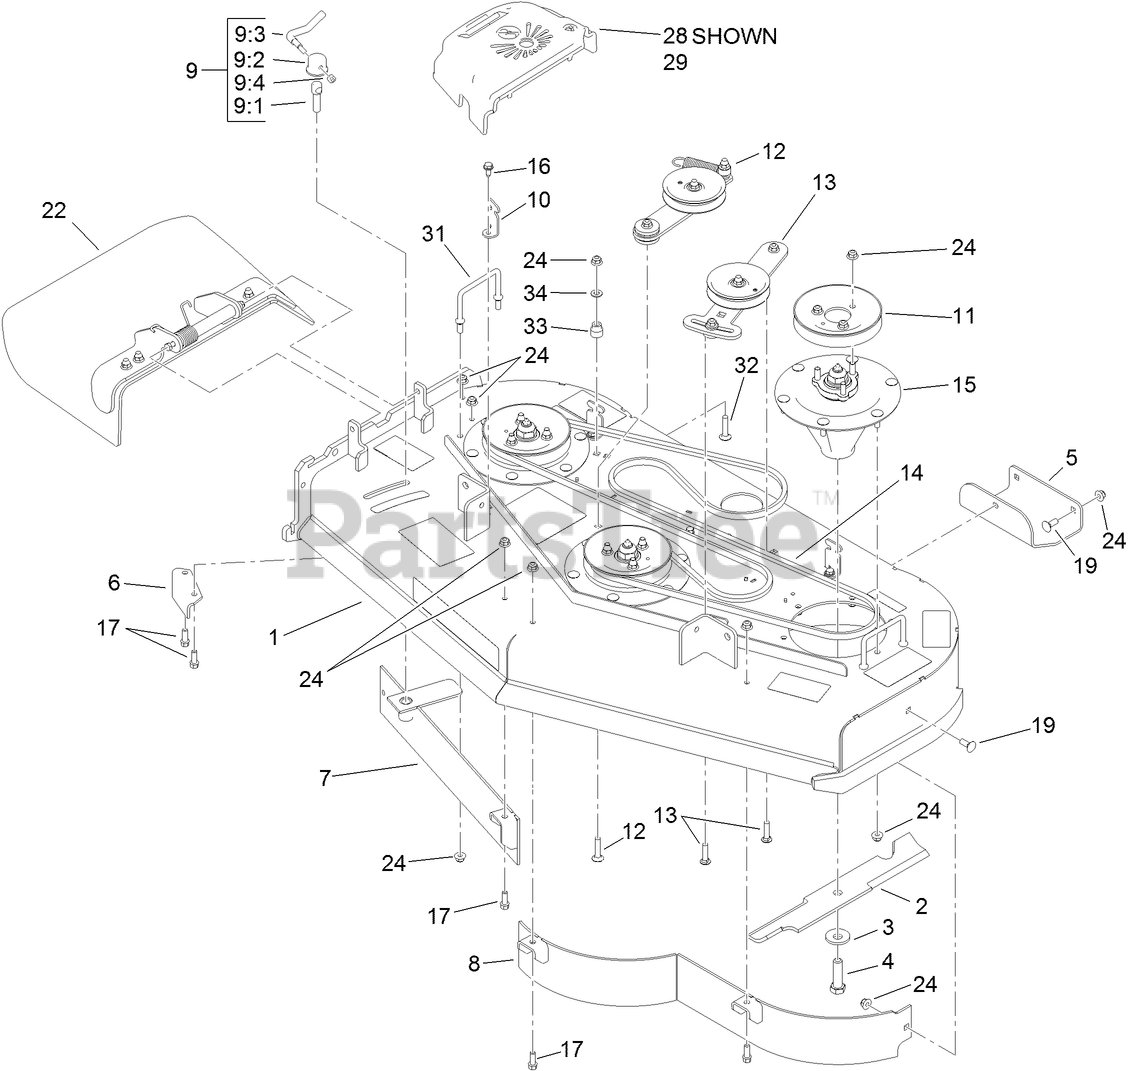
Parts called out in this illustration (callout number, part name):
1	DECK ASM
2	BLADE-16.5 INCH (HIGH FLOW)
3	Washer-Blade Bolt, Heavy
4	SCREW-BLADE
6	BAFFLE-DISCHARGE
7	BAFFLE ASM
8	48 INCH BAFFLE ASM
9	LEVER ASM
9:1	Screw-Lock
9:2	CAP-LOCK
9:3	Lever-Lock
9:4	NUT-LOCK, NI
10	BRACKET-COVER
11	PULLEY
12	IDLER ARM ASM
13	IDLER ADJUST ASM
14	BELT-V
15	SPINDLE ASM
16	SCREW-HWHTF
17	SCREW-HWH
19	BOLT-CARR
22	DEFLECTOR ASM
24	NUT-HF, NI
28	COVER-BELT, RH
29	COVER-BELT
31	WIREFORM-COVER
32	SCREW-CARR
33	BUSHING-IDLER
34	WASHER-FLAT
